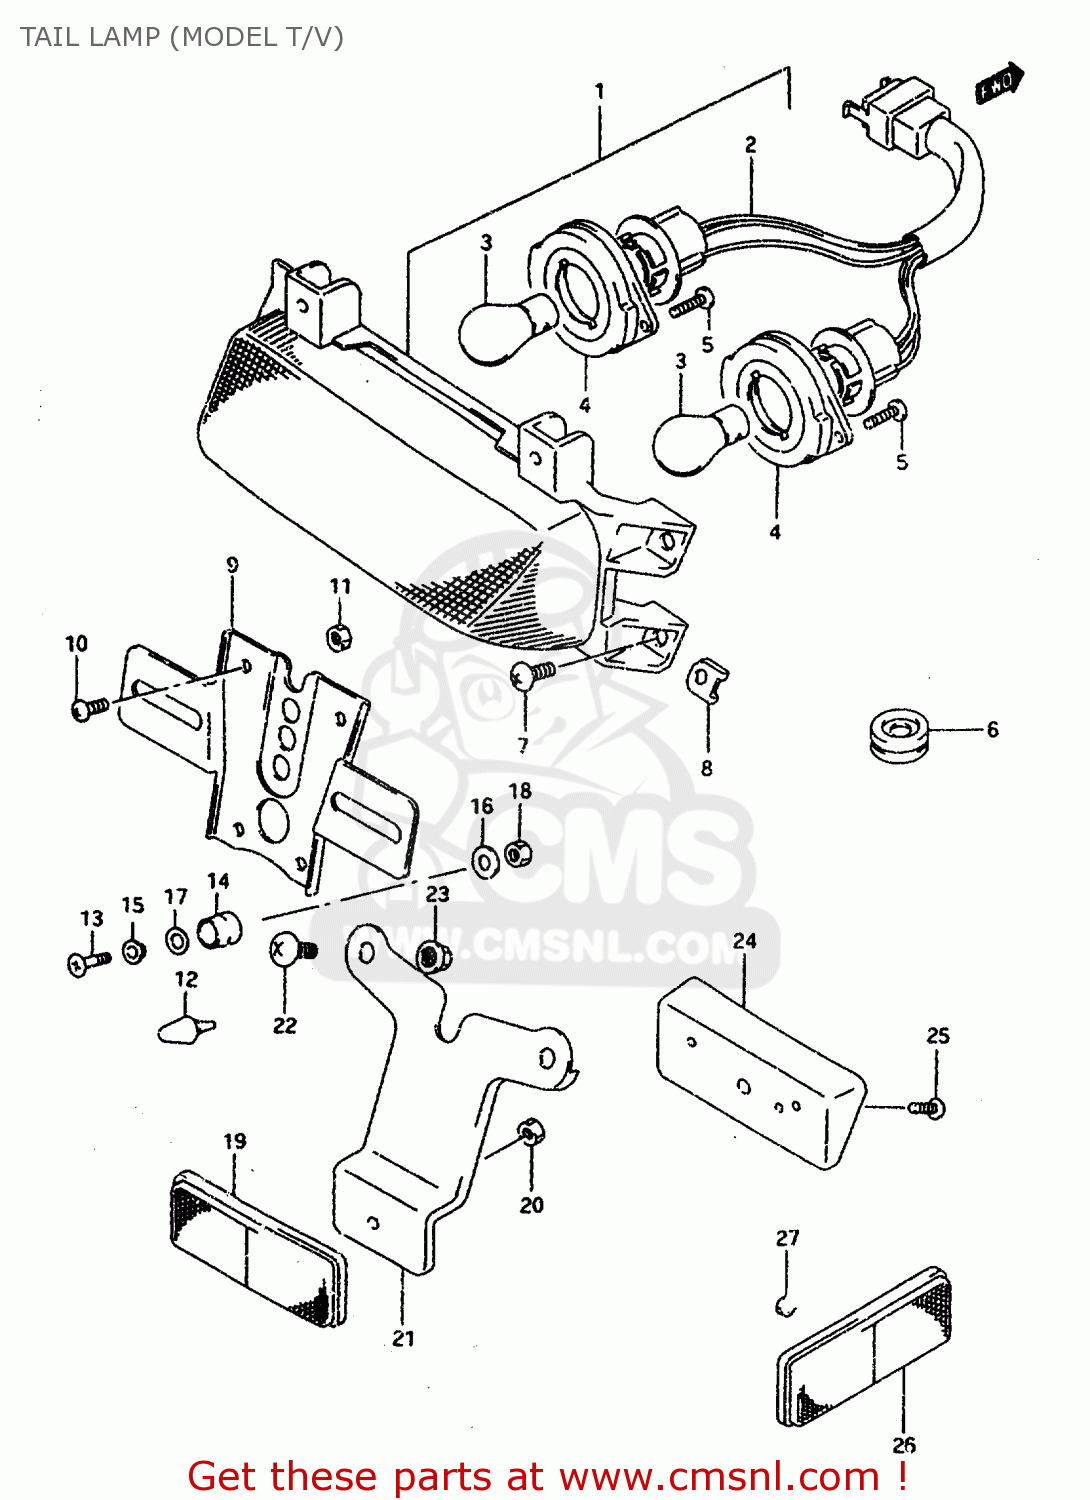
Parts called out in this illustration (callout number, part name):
1	LAMP ASSY, REAR COMBINATION
2	SOCKET & CORD ASSY
3	BULB(12V21/5W)
4	CUSHION
5	SCREW
6	GROMMET
7	SCREW 5X12
8	NUT
9	BRACKET,LICENSE PLATE
10	SCREW 6X12
11	NUT
12	CUSHION
13	SCREW
14	CUSHION, PLATE
15	WASHER
16	WASHER
17	WASHER(6.5X16X1.2)
18	NUT
19	REFLECTOR ASSY,RR
20	NUT
21	BRACKET,RR RR
22	SCREW 6X12
23	NUT
24	NUT
25	SCREW
26	SCREW
27	NUT
28	NUT
